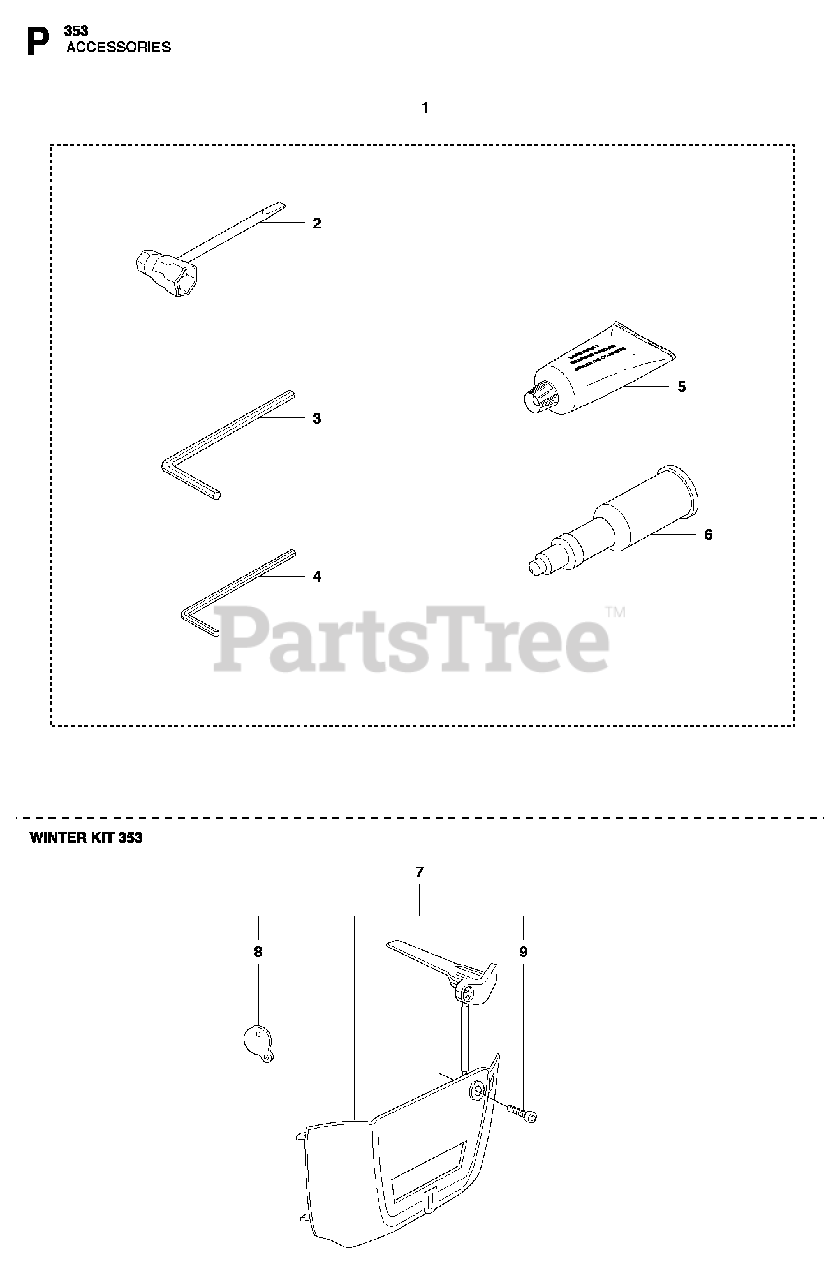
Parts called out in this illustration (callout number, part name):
1	TOOL KIT
2	COMBI TOOL
3	L-SPANNER
4	L-SPANNER
5	GREASE
6	Grease Gun
7	WINTER COVER
8	COVER
9	SCREW
